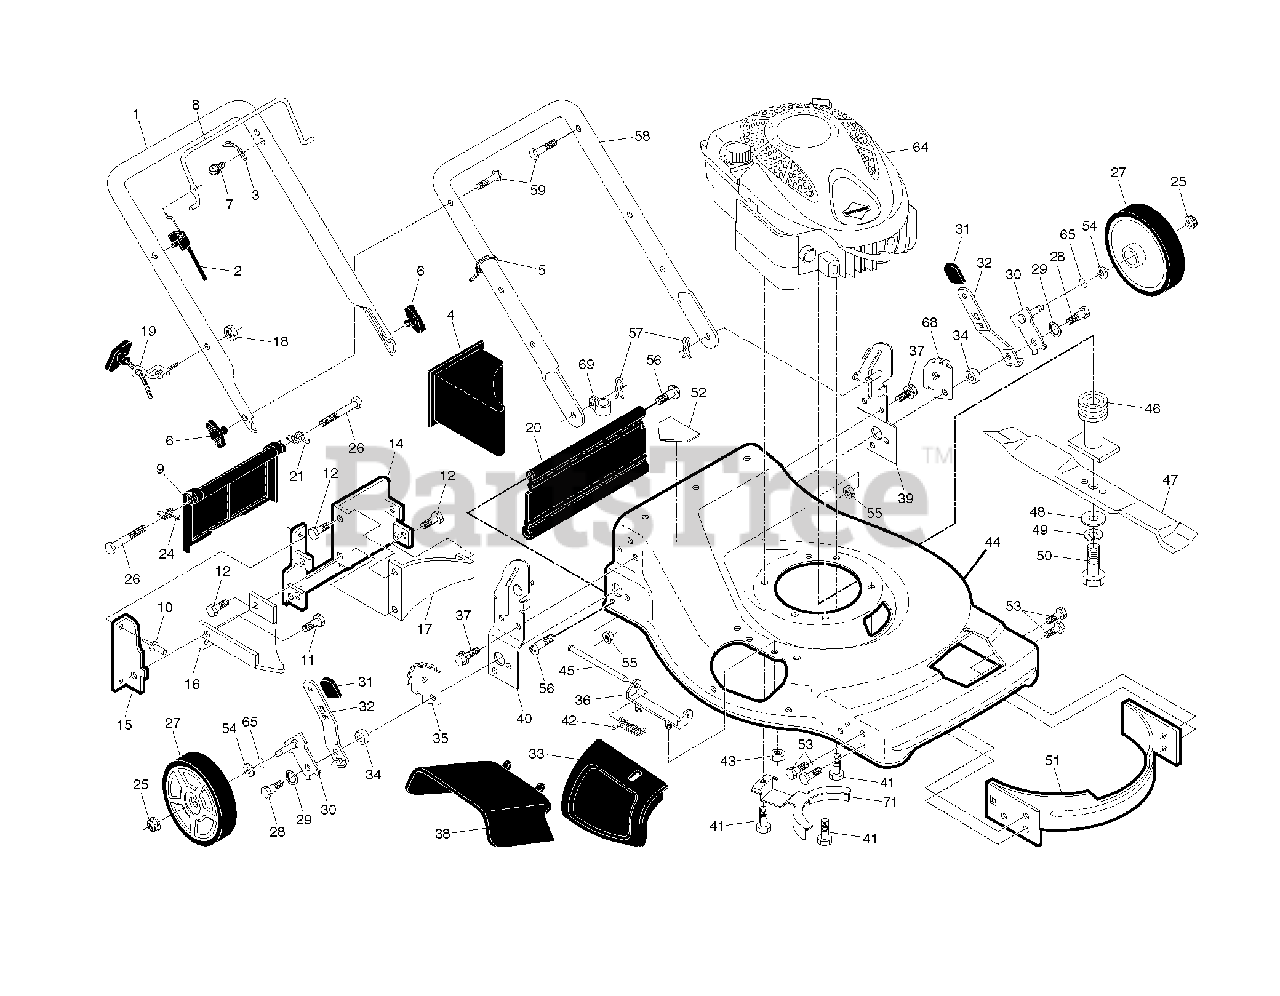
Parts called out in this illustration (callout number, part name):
1	HANDLE.UP.DSTR.FG/RGD.BLACK
2	CABLE.MZR
4	PLUG.MULCH.22RD
5	TIE GUIDE
6	KNOB.WING.PLASTIC.BLACK
8	BAIL.MZR.CURVED.YELLOW
9	REAR DOOR ASSY
10	RIVET BLIND
11	SCREW.HXTAP.10-24
12	SCREW 14-20 X 5/8
14	Back Plate
15	SIDE BAFFLE
16	DISCHARGE BAFFLE
17	REAR BAFFLE
18	NUT
19	GUIDE.ROPE.STD.BLK.ZIN
20	SKIRT.REAR.22RD/SD.FO/VE
21	SPRING.LH.22.REAR.DOOR.EZ.EMPT
24	SPRING.RH.22.REAR.DOOR.EZ.
25	NUT.HEX.FLANGE.3/8-16.LOCKNUT
27	WHEEL.8X1.75.CF5SPK.RAD.BLACK
28	BOLT SHOULDER 3/8 -16X1
29	WASHER.CURVED.CYLINDRICAL
30	AXLE ARM ASSY.
31	KNOB.ERGO.DLX.PLAS.MARI.MULTI
32	SELECTOR SPRING, FRONT
33	DOOR.MULCH.22.REAR.FWG.BLACK
34	SPACER.HEIGHT.ADJUSTER
35	Wheel Adjusting Bracket
36	BRACKET.ASM.HINGE.21.FWGD.
37	BOLT.HEX.HD.WASHER.5/16-18X.75
38	DEFLECTOR.CLIPPING.22.FGD.BLAC
39	Handle Bracket Assembly, LH
40	Handle Bracket Assembly, RH
41	BOLT 3/8-16X1-1/8
42	SPRING.TORSION
43	LOCKNUT.NYLOC.1/4-20
45	ROD.HINGE.21
46	ADAPTER.BLADE/PULLEY.25M
47	BLADE.22.MULCH.STANDARD
48	WASHER,HARDEN
50	SCREW, HEX HD 3/8-24 X 1-3/8
51	FRONT BAFFLE KIT
52	No Step Decal
53	SCREW 1/4X20
54	WASHER PM
55	LOCKNUT
56	HINGE SCREW
57	HAIRPIN COTTER
58	HANDLE.LOWER.D-STRAIT.BLACK
59	BOLT, HANDLE 5/16-18X1.75
65	O-RING..070X.487.NEOPRENE
68	Wheel Adjusting Bracket, LH
69	CLIP.CABLE.BLK
71	BRACKET.ENG/BELTKEEPER.BZP
